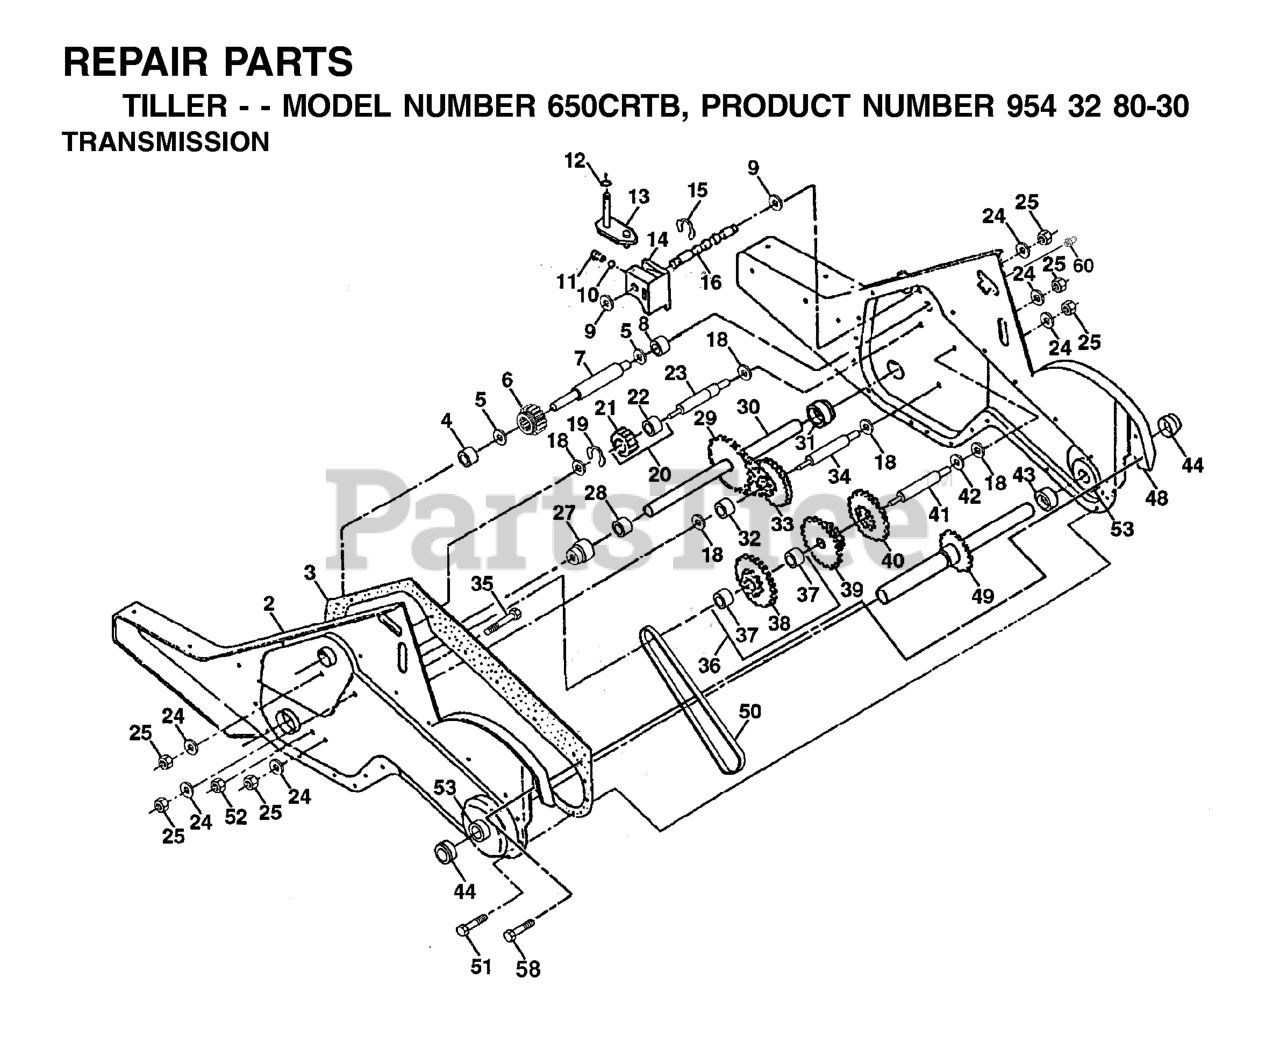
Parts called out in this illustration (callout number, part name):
1	TRANS SERV
2	GEAR CASE
3	GASKET
4	NEEDLE BRNG LT
5	THRUST WASHER
6	GEAR.PINION.INPUT
7	SHAFT.INPUT."D".TILLER
8	BEARING TI
9	WASHER, SEAL (2 2)
10	STEEL BALL KIT
11	SPRING-SHIFT CRT
13	BRACKET ASM.SHIFT.CRT
14	SHIFT FORK TI
16	SHAFT.SHIFTER.TILLER
20	GEAR ASSY CRT
21	GEAR-REV IDLR CRT
22	NEEDLE BEARING TI
24	LOCKWASHER
25	NUT.ASF.HEX.7/16
27	BEARING, SHAFT LH CRT
30	GROUND SHAFT ASS'Y
31	BEARING, SHAFT RH CRT
33	SPRCKT 8 GEAR CRT
34	SHAFT.SECONDARY.REDUCTION.CRT
35	SCRW WHIZ LOK CRT
36	SPROCKET.ASM.W/BEARING.TILLER
37	BEARING
38	SPROCKET, TINE
41	SHAFT.REDUCTION.TILLER
42	BRNG RACE T
44	SEAL ASM, OIL
48	GEARCASE, R.H. W/BEARING
49	TINE SHAFT
50	CHAIN.TILLER
51	SCREW
53	KIT.BEARING.TILLER.
58	BOLT SHOULDER 1/4-20 UNC X.875
60	ZERK M
